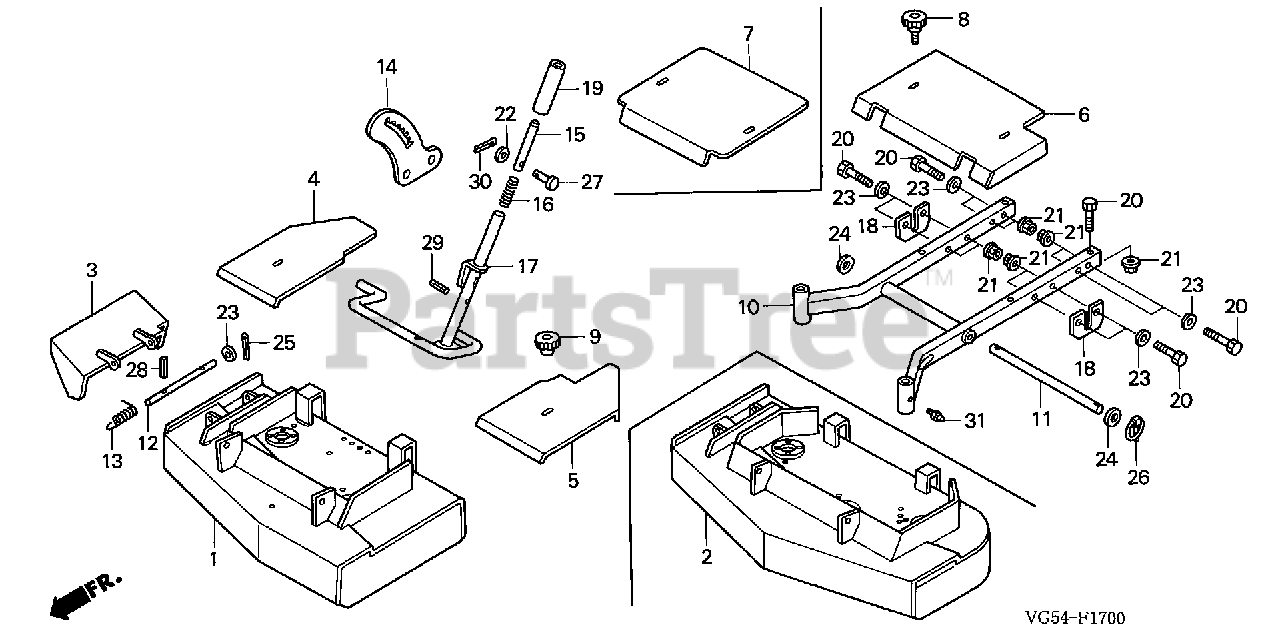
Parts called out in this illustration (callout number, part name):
2	HOUSING, CUTTER (48")
3	ADAPTER, DISCHARGE
4	COVER, R. BELT
5	COVER, L. BELT
7	COVER, BELT (48")
8	KNOB, BELT COVER (5/16-18 X 2")
9	KNOB, BELT COVER (5/16-18)
10	SUPPORT, CUTTER (48")
11	LINK, FR. DECK
12	SHAFT, DISCHARGE CHUTE
13	SPRING, GUARD RETURN
14	PLATE, RATCHET
16	SPRING, PUSH ROD
18	BRACKET, LIFTER
19	GRIP, HEIGHT ADJUSTMENT
20	BOLT, HEX. (1/2-13X2 1/2")
21	NUT, WHIZ-LOCK (1/2"-13)
22	WASHER, FLAT (3/8")
23	WASHER, FLAT (1/2")
24	WASHER, FLAT (3/4")
25	PIN, COTTER (1/8X1")
26	PIN (3/16")
27	PIN, HEIGHT ADJUSTING LEVER
28	PIN, ROLL (3/16X2 1/4")
29	PIN, ROLL (1/4X1")
30	PIN, COTTER (1/16"X1/2")
31	NIPPLE, GREASE
